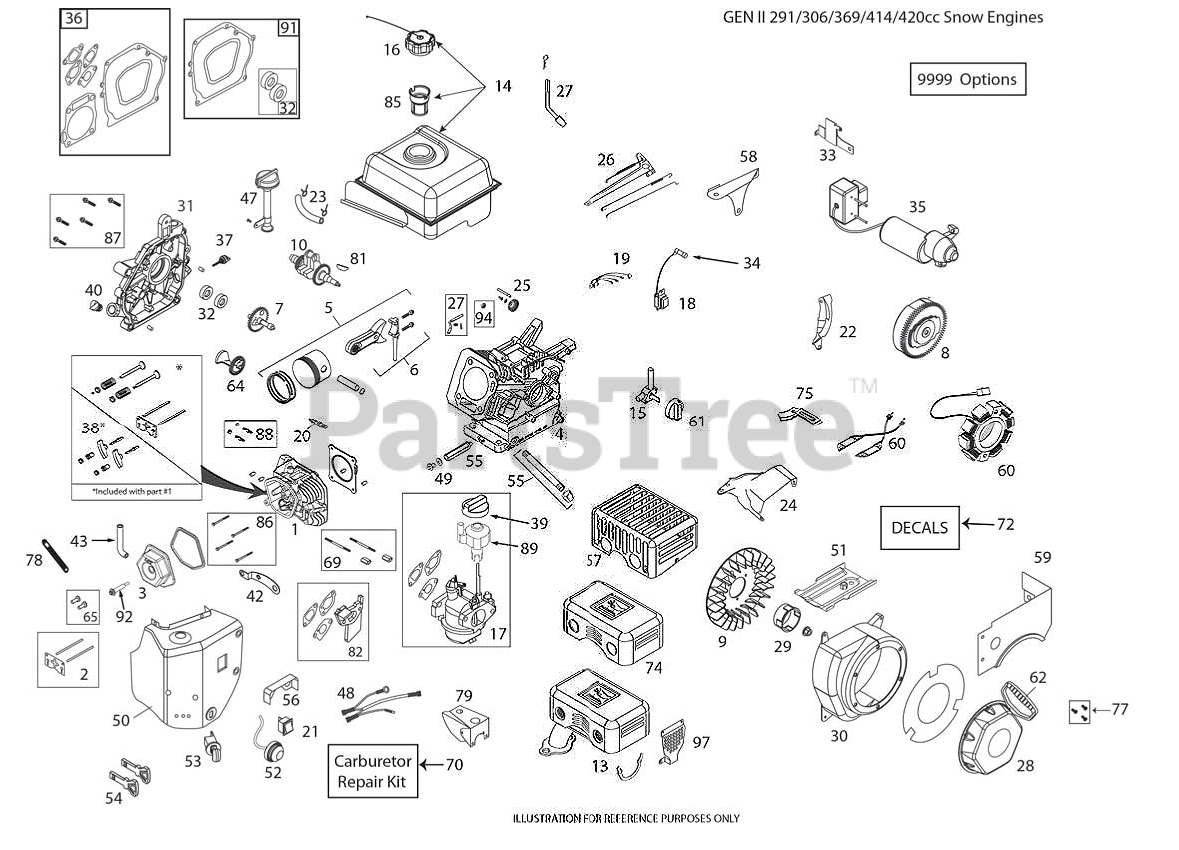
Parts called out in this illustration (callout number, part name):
1	CYLINDER.HEAD.ASSY(SK2911000)
2	PUSH ROD TAPPET KIT
3	VALVE.COVER.LCT.414CC.
4	CYLINDER ASSY SNO.LCT
5	PISTON.AND.ROD.ASSY(SK2911400)
6	CONNECTING ROD ASSY SNO.LCT
7	CAMSHAFT.LCT.291CC
8	FLYWHEEL.EL.ST.SKSNO2401.1
9	FLYWHEEL.FAN
10	CRANKSHAFT
13	MUFFLER ASSY LCT SNO
14	FUEL TANK ASSY - SNOW (291CC)
15	FUEL.PETCOCK.SNOW(SKSN4900)
16	FUEL.TANK.CAP.SNOW(SKSN4301)
17	CARBURETTOR LCT
18	COIL.IGN.CDI.SKSN2403.1
20	SPARK.PLUG(SK2911550)
21	ON/OFF.SWITCH.SNOW(SKSN4403)
23	FUEL HOSE KIT
24	TOP.SHIELD.LCT.
25	GOVERNOR.GEAR.ASSY(SK2912900)
26	GOVERNOR.ARM.ASSY.(SKSN2502)
27	GOVERNOR.SHAFT.(SK2913100)
28	STARTER RECOIL.291/306CC.LCT
29	STARTER CUP.LCT.291/306CC
30	BLOWER HOUSING.LCT.291/306CC W
31	CRANKCASE.COVER.ASY(SK2913600)
32	OIL.SEAL.KIT(SK2913900)
33	SWITCHBOX BRACKET ES LCT 291 S
34	SPARK.PLUG.BOOT.SNW,SKSN4691.1
35	STARTER, ELECTRIC, 230V
36	ENGINE.GASKET.KIT(SK2914300)
37	DIPSTK.OIL.BLK.LCTSK4143711.1
38	ROCKER ARM KIT
39	CHOKE.KNOW.SNOW(SKSN4500)
40	NONREMVABLE.OIL.PLUG(SK4143715
42	CDI.BOX.BRKT.SNOW(SKSN4402)
43	BREATHER TUBE LCT 291/369/414
47	HIGHOIL.FILL.ASSY.KIT(SKSN4911
48	WIRE.HARNESS(SKSN4406)
50	HEATER.BOX.ASSY.SNOW(SKSN2100)
51	SHIELD.CYLINDER.SNOW(SK4141010
52	PRIMER.BULB.ASSY(SKSN4304)
53	KEY.SWITCH.ASSY.SNOW(SKSN4401)
54	KEY SET(2 KEYS) SKSN0407.1
55	OIL PIPE DRAIN EXTENDED.LCT SK
56	SHIELD.VAPOR(SKSN4606)
57	MUFFLER GUARD.CE.LCT
58	GOVERNOR.LINK.SHIELD(SKSN2501)
59	FUEL TANK SKIRT.LCT.291/306CC
60	ALTERN.60WATT.SKSN2402.1
61	FUEL KNOB-SNOW
62	HANDLE.RECOIL.DELUXE.LCT
65	TAPPET KIT.LCT.SK2911005.1
69	STUD.CARB.MOUTING.KIT.291CC
70	CARBURETTOR REPAIR KIT 291CC/4
74	MUFFLER SHIELD
75	WIRE GUARD
77	BOLT.KIT.RECOIL.LCT.ALL.ENGINE
79	SHIELD CARBURRETOR COVER 414
81	KEYS.FLYWHEEL.136/291CC.5PACK
82	SPACER.CARBURETOR.291CC.LCT
85	STRAINER.FUEL.TANK.LCT.208CC
86	KIT.BOLT.CYLINDER.HEAD.(4PC)
87	KIT.7-BOLT.CRANKCASE.CVR.291CC
88	STUD.MUFFLER.KIT.LCT
89	KNOB LCT.SKSN5325.1 SPEED
91	GASKET KIT CRANKSHAFT.LCT
92	CENTER VALVE COVER BOLT
9999	HIGH.ALTITUDE.JET.6000FT ANDUP
9999	KIT.BOLT.LCT.SK9990.1
